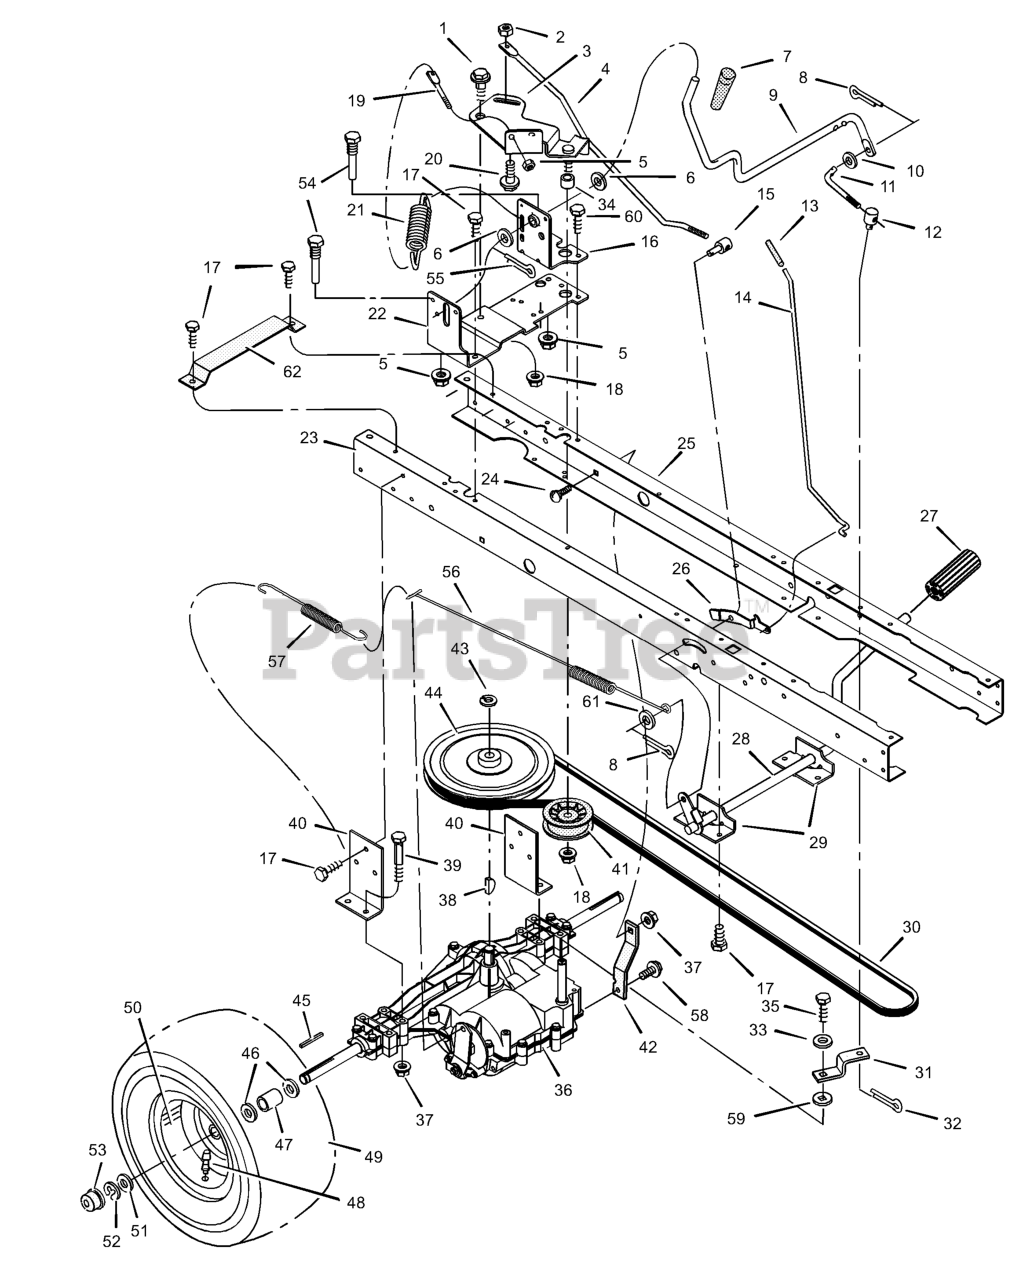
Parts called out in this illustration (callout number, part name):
1	Bolt, Shoulder
2	Nut, Hex
3	ARM, Idler
4	Rod, Clutch
5	Nut
6	Washer
7	Grip
8	Pin, Cotter
9	Lever, Shift
10	Washer
11	Link, Shift
12	Nut, Adjuster
14	Rod, Parking Brake
15	Nut, Adjuster
16	Bracket, Shift Pivot
18	Nut
19	Mount, Stud Spring
20	Bolt, Shoulder
21	Spring, Extension
22	Bracket, Right Shifter
23	Frame, Right
24	Bolt, Carriage
25	Frame, Left
26	Latch, Parking Brake
27	Pedal
28	Lever, Brake/Clutch
29	Bracket, Pedal
30	Belt, Motion Drive
31	Yoke, Shift
32	Pin, Hair
36	Transaxle **
37	Nut
38	Key, Woodruff
39	Bolt
40	Bracket, Transaxle
42	BRACKET, Torque Strap, LH
44	Pulley, Drive
45	Key, Square
47	Spacer, Transaxle
48	Stem, Valve
50	Wheel & Tire Assembly
53	Hub Cap
54	Guide, Belt
55	Pin, Hair
56	Spring, Extension
57	Spring, Extension
61	Washer
62	Bracket, Battery Support
